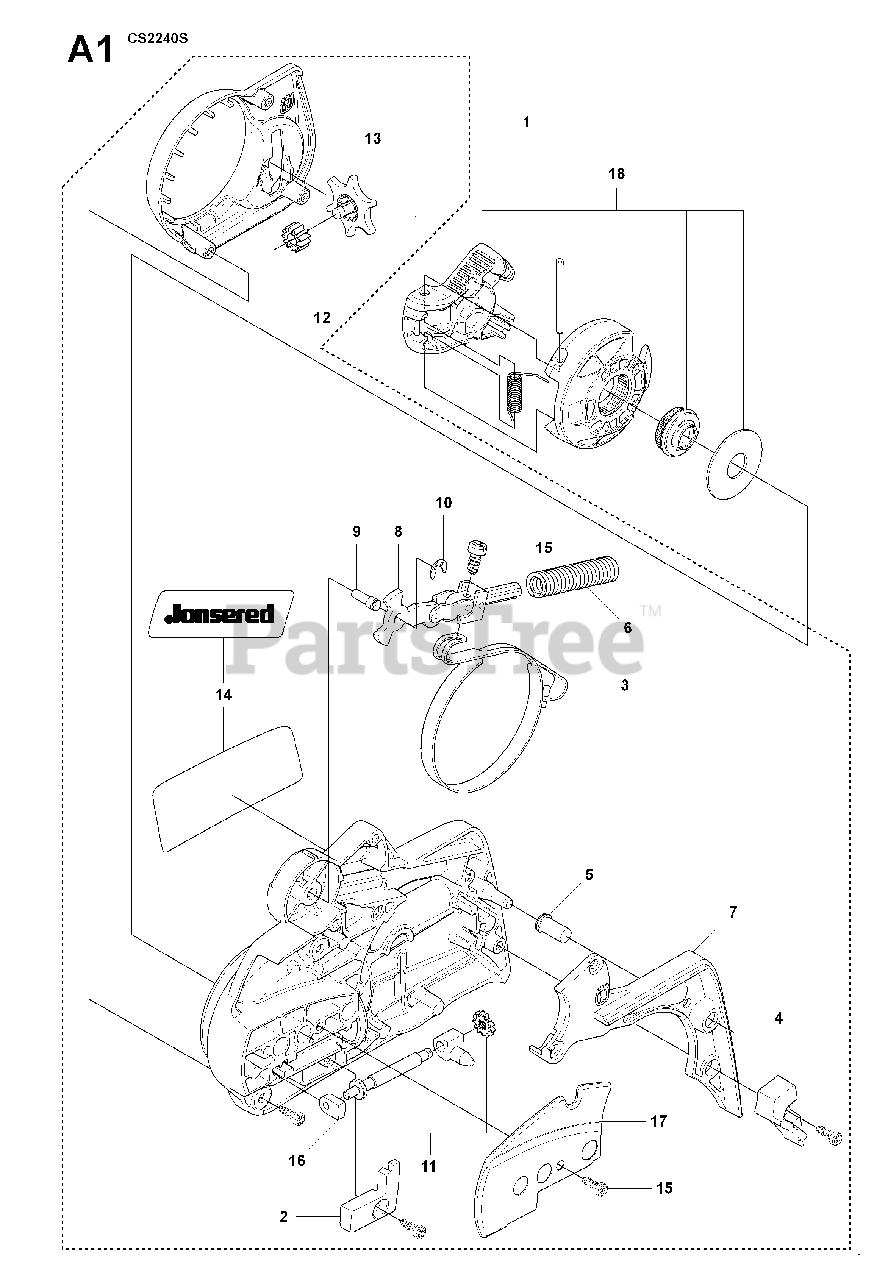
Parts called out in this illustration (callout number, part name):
1	CLUTCH COVER ASSY
3	BRAKE BAND ASSY
4	WEAR PROTECTION
6	BRAKE SPRING
11	CHAIN TENSIONER SCREW, COMP.
12	CHAIN TENSIONER WHEEL
16	RP BEARING SLEEVE
